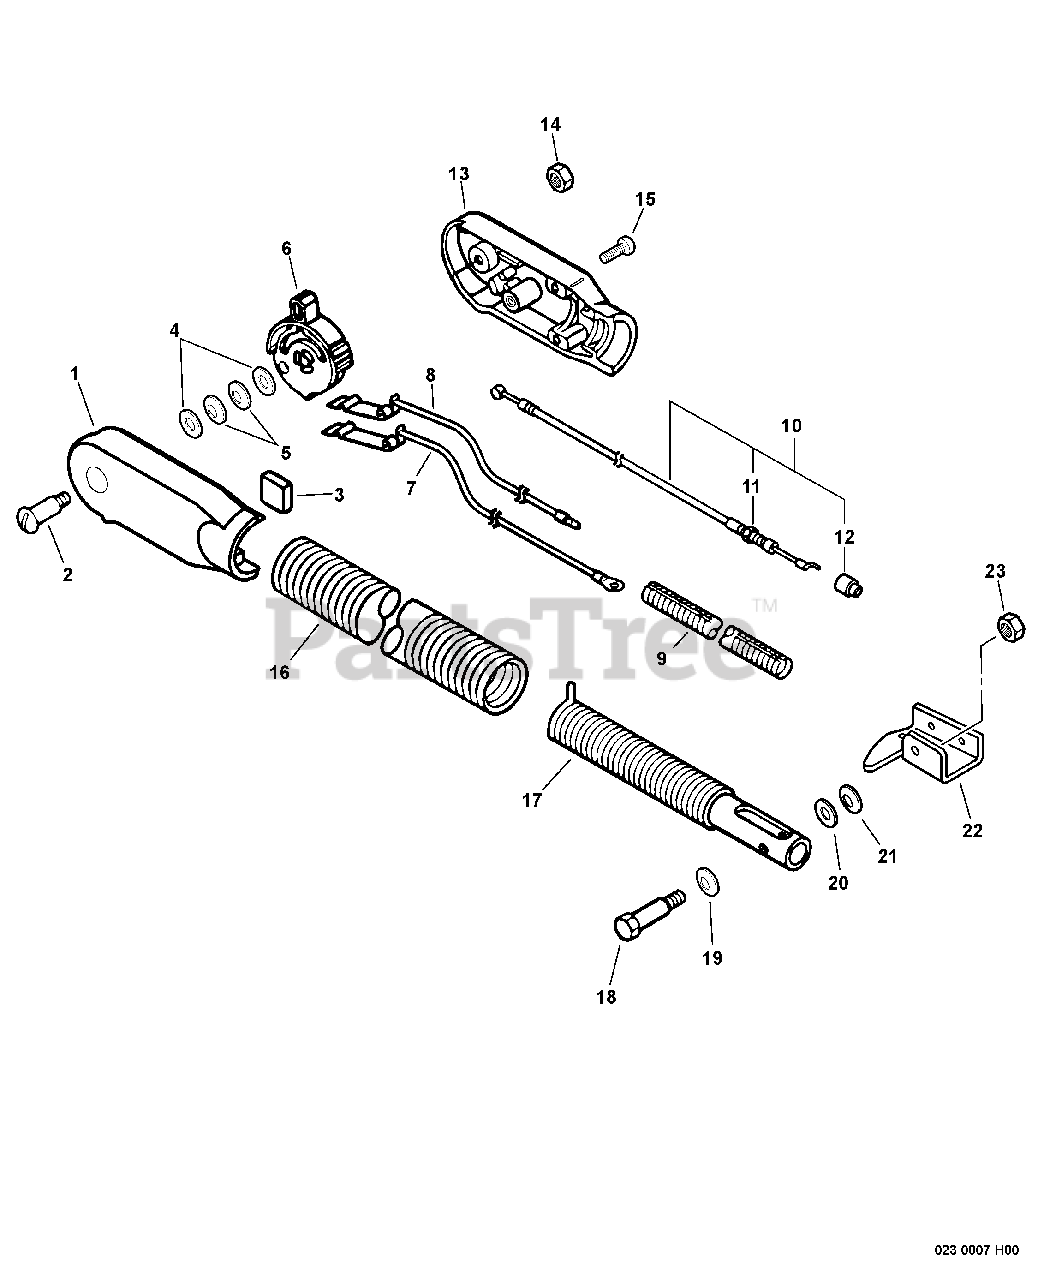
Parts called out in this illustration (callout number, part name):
1	HOUSING, THROTTLE - LEFT
3	PAD, FOAM
4	WASHER 6.5×15.5×0.6
5	WASHER, FRICTION 6.6×14.3
6	LEVER, THROTTLE
7	LEAD, SWITCH
8	LEAD - IGNITION
9	TUBE, PROTECTIVE - CORRUGATED
10	THROTTLE CABLE ASSY
11	NUT, HEX M6
12	CAP, DUST
13	HOUSING, THROTTLE - RIGHT
14	NUT, LOCK 4
16	TUBE, OUTER
17	SPRING TUBE ASSY
19	WASHER, WAVE
20	WASHER 8
21	WASHER 8
